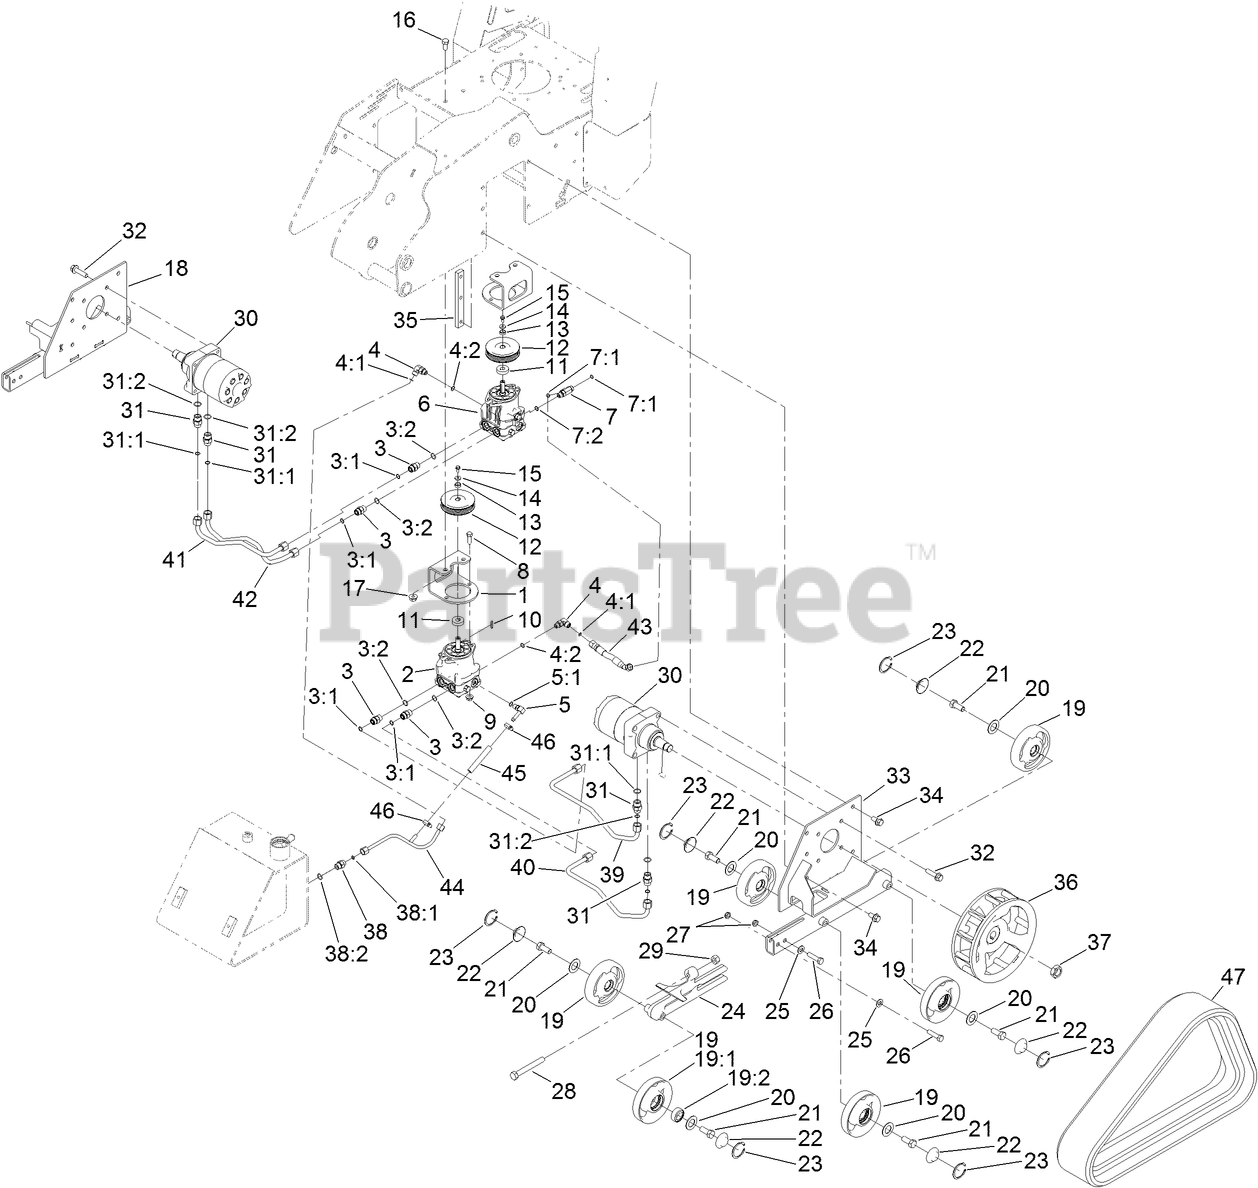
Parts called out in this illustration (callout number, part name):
1	BRACKET-MOUNT, PUMP
2	RH HYD PUMP ASM
3	FITTING-STRAIGHT
3:1	O-RING
3:2	O-RING
4	FITTING-ELBOW, 90 DEG
4:1	O-RING
4:2	O-RING
5	FITTING-ELBOW, 90
5:1	O-RING
6	LH HYD PUMP ASM
7	FITTING-TEE
7:1	O-RING
7:2	O-RING
8	SCREW-HH
9	NUT-HF
10	KEY-PUMP
11	SPACER
12	SHEAVE
13	BUSHING
14	WASHER
15	SCREW-HHF
16	SCREW-HH
17	NUT-HHF
18	FRAME-TRACK, RH
19	WHEEL-TENSIONER
19:1	WHEEL-TRACK
19:2	BEARING-BALL
20	Gasket-Bogie
21	SCREW-HH
22	CAP-WHEEL, BEARING
23	RING-SNAP, INTERNAL
24	TENSIONER-TRACK
25	WASHER-FLAT
26	SCREW-HH
27	NUT-LOCK, NI
28	SCREW-HH, TAP
29	NUT-HEX
30	HYD WHEEL MOTOR ASM
31	FITTING-STRAIGHT
31:1	O-RING
31:2	O-RING
32	SCREW-HHF
33	FRAME-TRACK, LH
34	SCREW-HHF
35	BAR-THREAD
36	WHEEL-DRIVE
37	NUT-LOCK
38	FITTING-STRAIGHT
38:1	O-RING
38:2	O-RING
39	TUBE-HYD
40	TUBE-HYD
41	TUBE-HYD
42	TUBE-HYD
43	HOSE-HYD
44	TUBE-HYD
46	CLAMP-HOSE
47	TRACK-RUBBER
